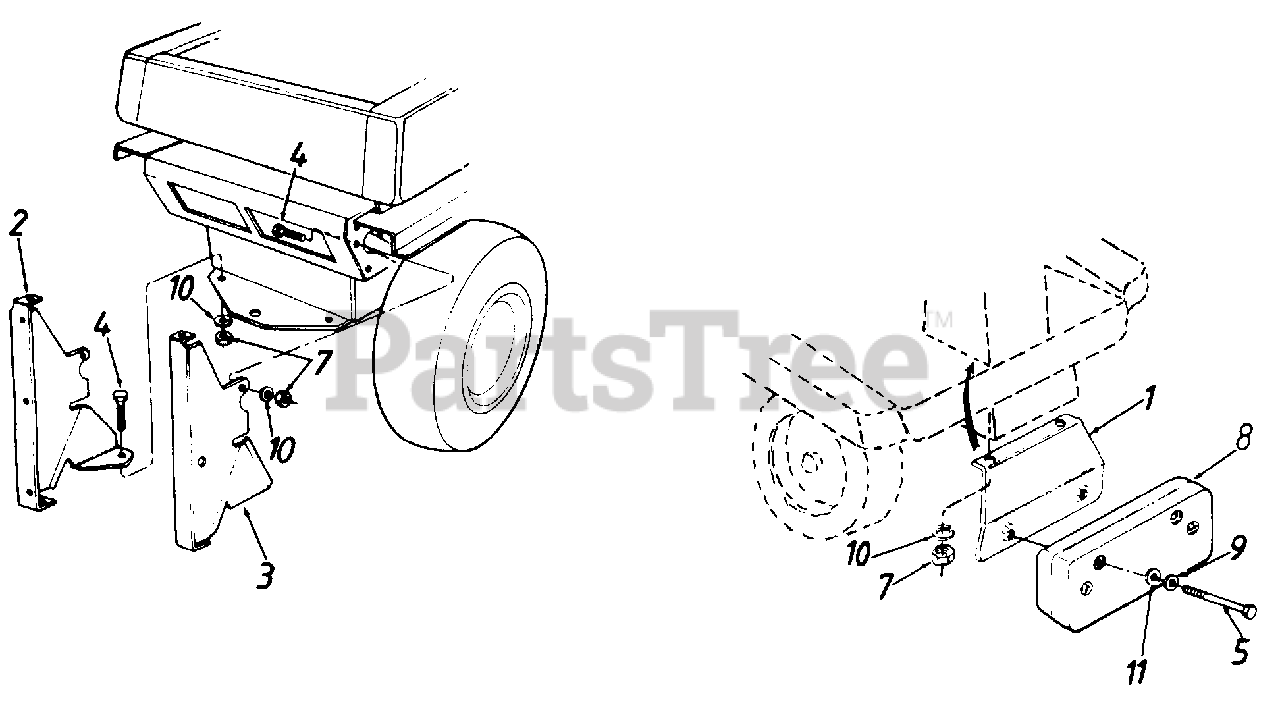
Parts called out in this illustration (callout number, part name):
1	Counterweight Support Brkt.
2	Catcher Support Brkt. R.H.
3	Catcher Support Brkt. L.H.
4	Hex Bolt 5/16-18 x 1.0" Lg.
5	Hex Bolt 3/8-16 x 4.5" Lg.
7	Hex Nut 5/16-18 Thd.
8	Front Counterweight
9	Bell-Wash. 3/8" I.D.
10	L-Wash. 5/16" I.D.
11	Fl-Wash. .390" I.D. x 1.12" O.D
